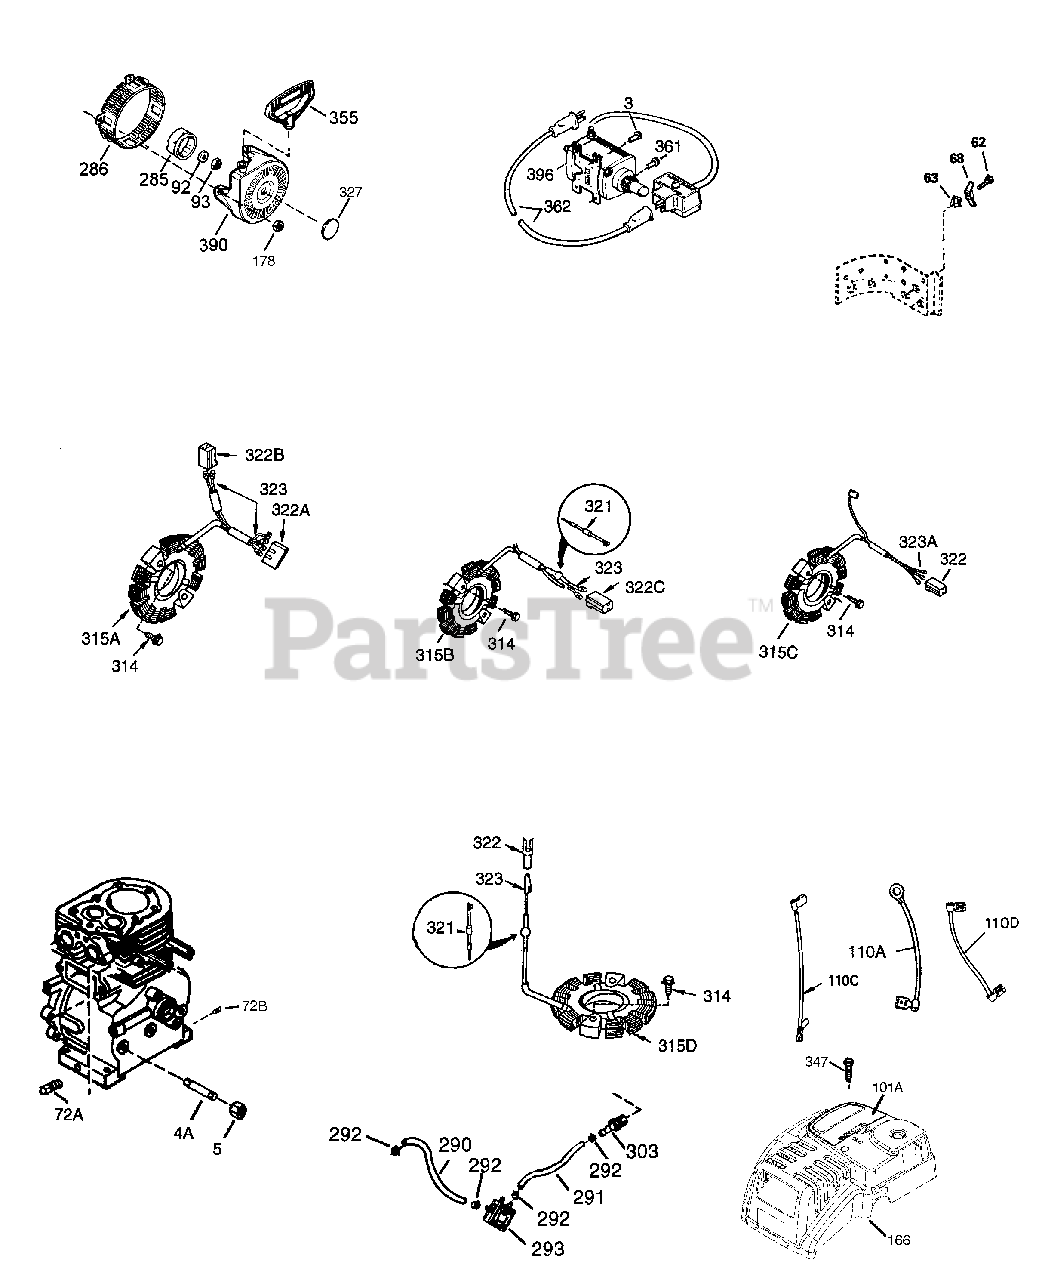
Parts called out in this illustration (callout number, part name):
3	Screw, 1/4-20 x 1/2" (Upper Mounting Screws for 120-Volt Electric Starter Motor)
5	Extension Cap
41	Piston & Pin Ass'y. (Std.) (Incl. 43)
41	Piston & Pin Ass'y. (.010" OS) Incl. 43
62	Screw, 8-32 x 3/8"
92	Belleville Washer
93	Flywheel Nut
110A	Ground Wire (10.50" with male & femal e flag terminals)
178	Nut & Lock Washer 1/4-28
285	Starter Cup
291	Fuel Line
292	Fuel Line Clamp
314	Screw, 1/4-20 x 3/4"
323	Terminal
327	Starter Plug
355	Starter Handle (Mitten Grip) also ava ilable in Packaged Part #740053B
390	Rewind Starter NOTE: This engine cou ld have been built with 590733 starte r.
396	Electric Starter Motor (Optional)
900	Replacement Short Block, order from 7 1-999
900	Replacement Engine, order from 71-999
999	Winter Maintenance Kit incl. 5W30 Oil , Spark Plug, Key, & Ultra-Fresh
999	Winter Maintenance Kit (incl. 0W30 Sy nthetic Oil, Spark Plug, Key, & Ultra -Fresh)
